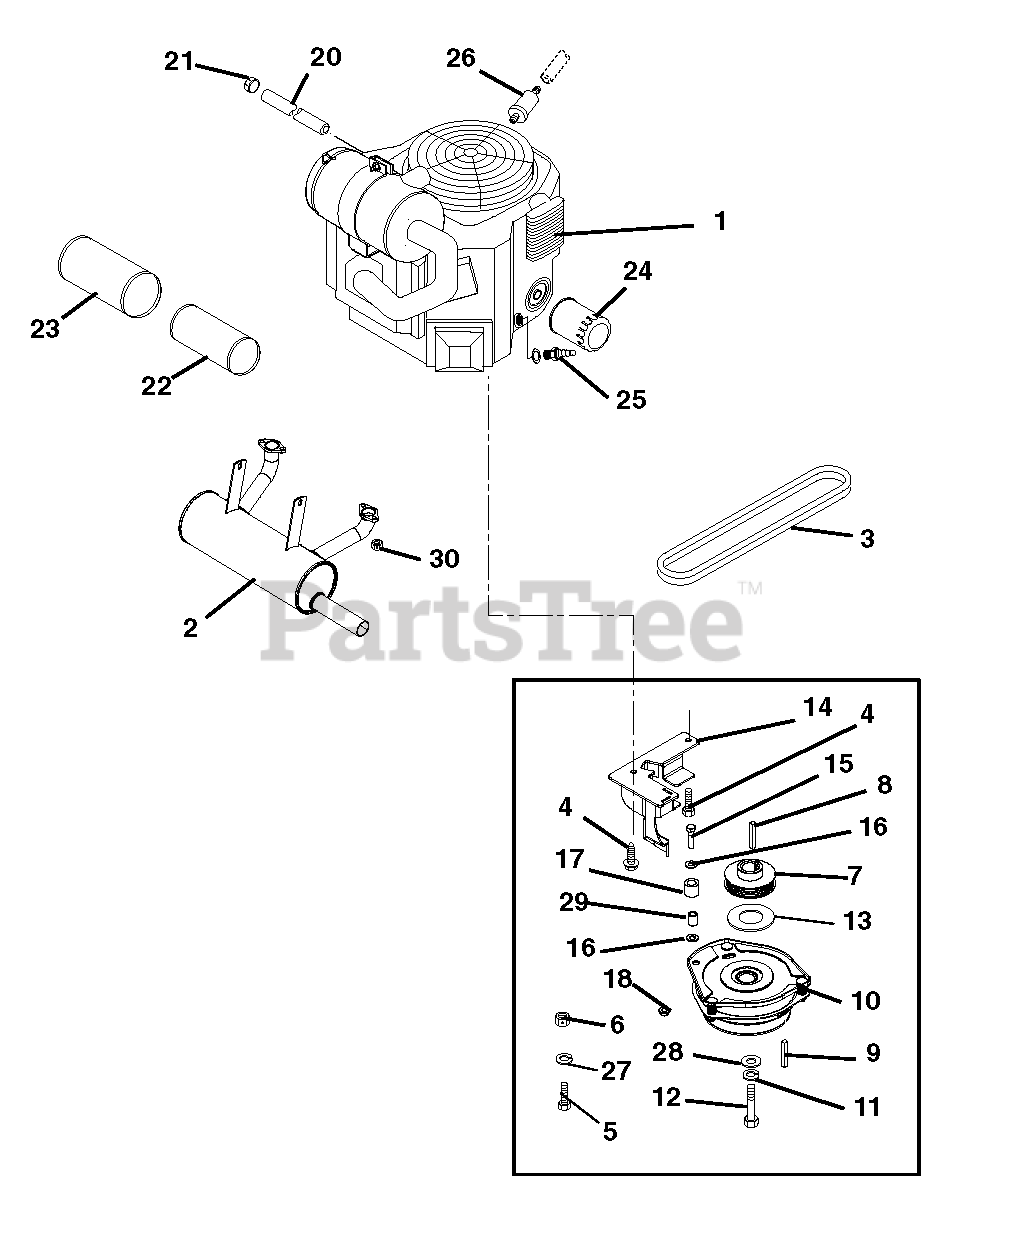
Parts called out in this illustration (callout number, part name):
1	Engine, Generac GTV990 (LPG)
2	Muffler, Generac GTV990 (LPG)
3	Belt, Poly-V
4	Screw, Tapping Hex Washer Head .38-16 x 1.
5	Bolt, Hex .31-18 x 1.75 Grade 5
6	Nut, Locking Top Flange .31-18
7	Sheave, Poly V 1.27 x 3.275
8	Key-Square .25 x 1.25 x .25 SAE
9	Key-Straight .25 x 1.75 x .25
10	Clutch, Electric
11	Washer, Locking .44 x .109
12	Bolt, Hex .44-20 x 2.25 Grade 5
13	Washer, 1.13ID x 1.75OD x .048 Steel
14	Anchor Clutch
15	Bolt-Hex .38-16 x 1.50 Grade 5
16	Washer-Flat-Steel .406 x .812 x .065
17	Bumper, Rubber .62 x 1.0 x .88 LG
18	Nut-Locking-Top-Flange .38-16
19	Cable Tie LG 5-1/2
20	Hose, Hydraulic .38-11-0K M6N0-M6N0
21	Pipe Cap .38 NPT Female
22	Element, Inner Safety
23	Element, Outer Primary
24	Oil Filter
25	Spark Plug
26	Fuel Filter
27	Washer, Locking-EXT.326 x .599 x .031
28	Washer, Flat Steel .469 x 2 x .25
29	Bushing, .407 x .625 x .813
30	Nut, Locking, Top M8-1.25
